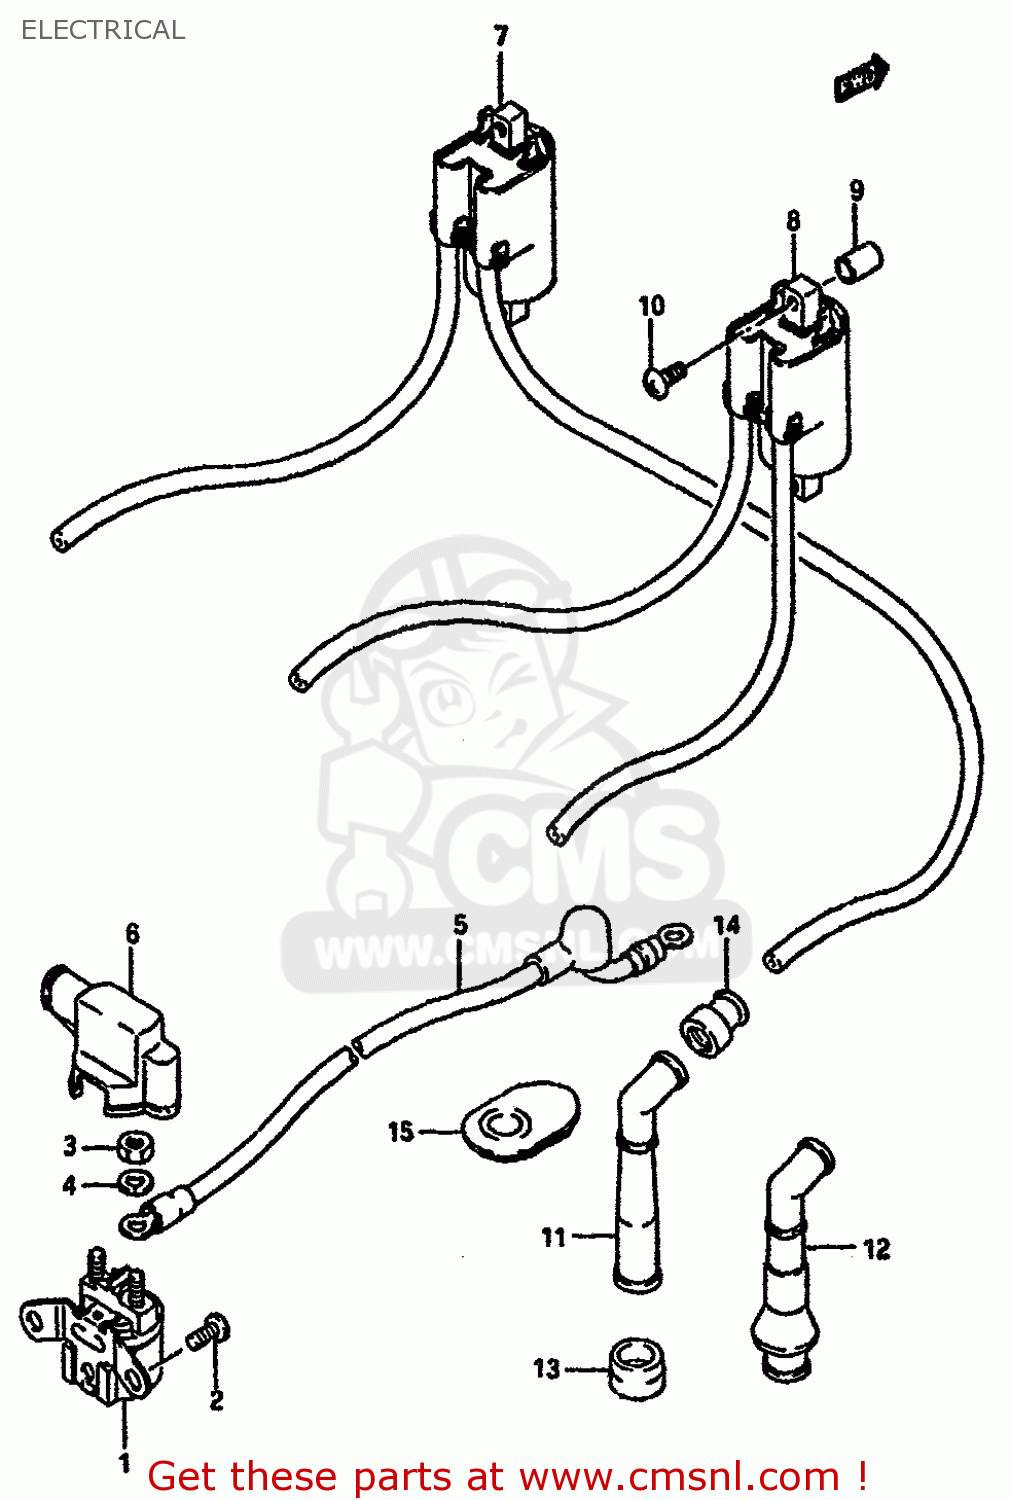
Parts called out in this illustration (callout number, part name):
1	RELAY ASSY,STARTING MOTOR
2	SCREW
3	NUT
4	WASHER,LOCK
5	WIRE,STARTER MOTOR LEAD
6	CAP,STARTER RELAY
7	COIL ASSEMBLY,IGNITION
8	COIL ASSEMBLY,IGNITION
9	SPACER
10	SCREW
11	CAP,SPARK PLUG
12	CAP, SPARK PLUG
13	SEAL,SPARK PLUG
14	SEAL,SPARK PLU
15	COVER,SPARK PLUG CAP
